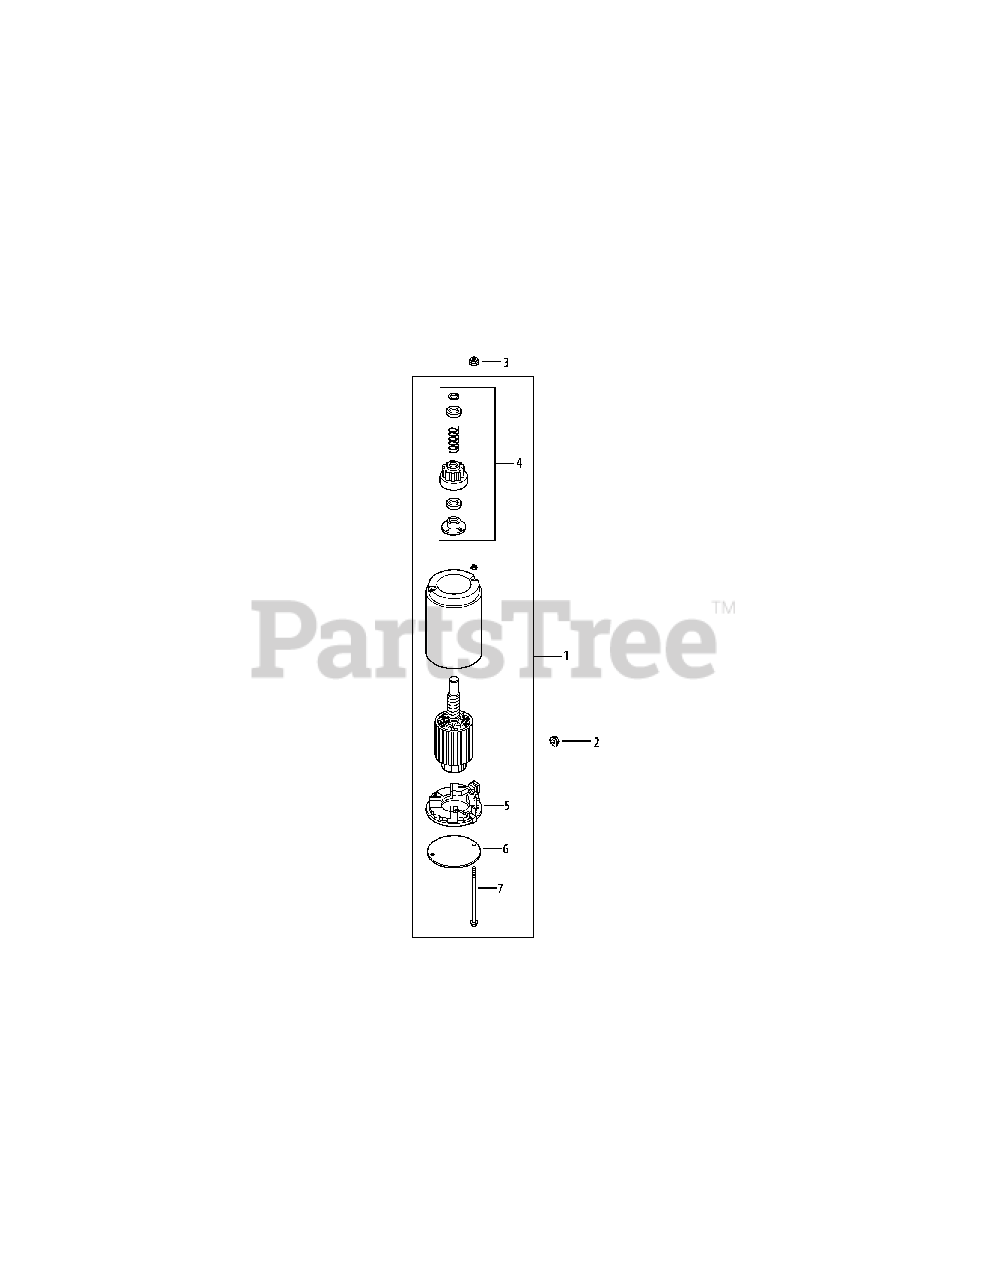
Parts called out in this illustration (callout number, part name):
1	Starter Assembly (Inc. 4-7)
3	Free Spinning Flange. Nut, #10-24
4	Drive Kit (J.E.)
6	Drive End Cap (J.E.)
